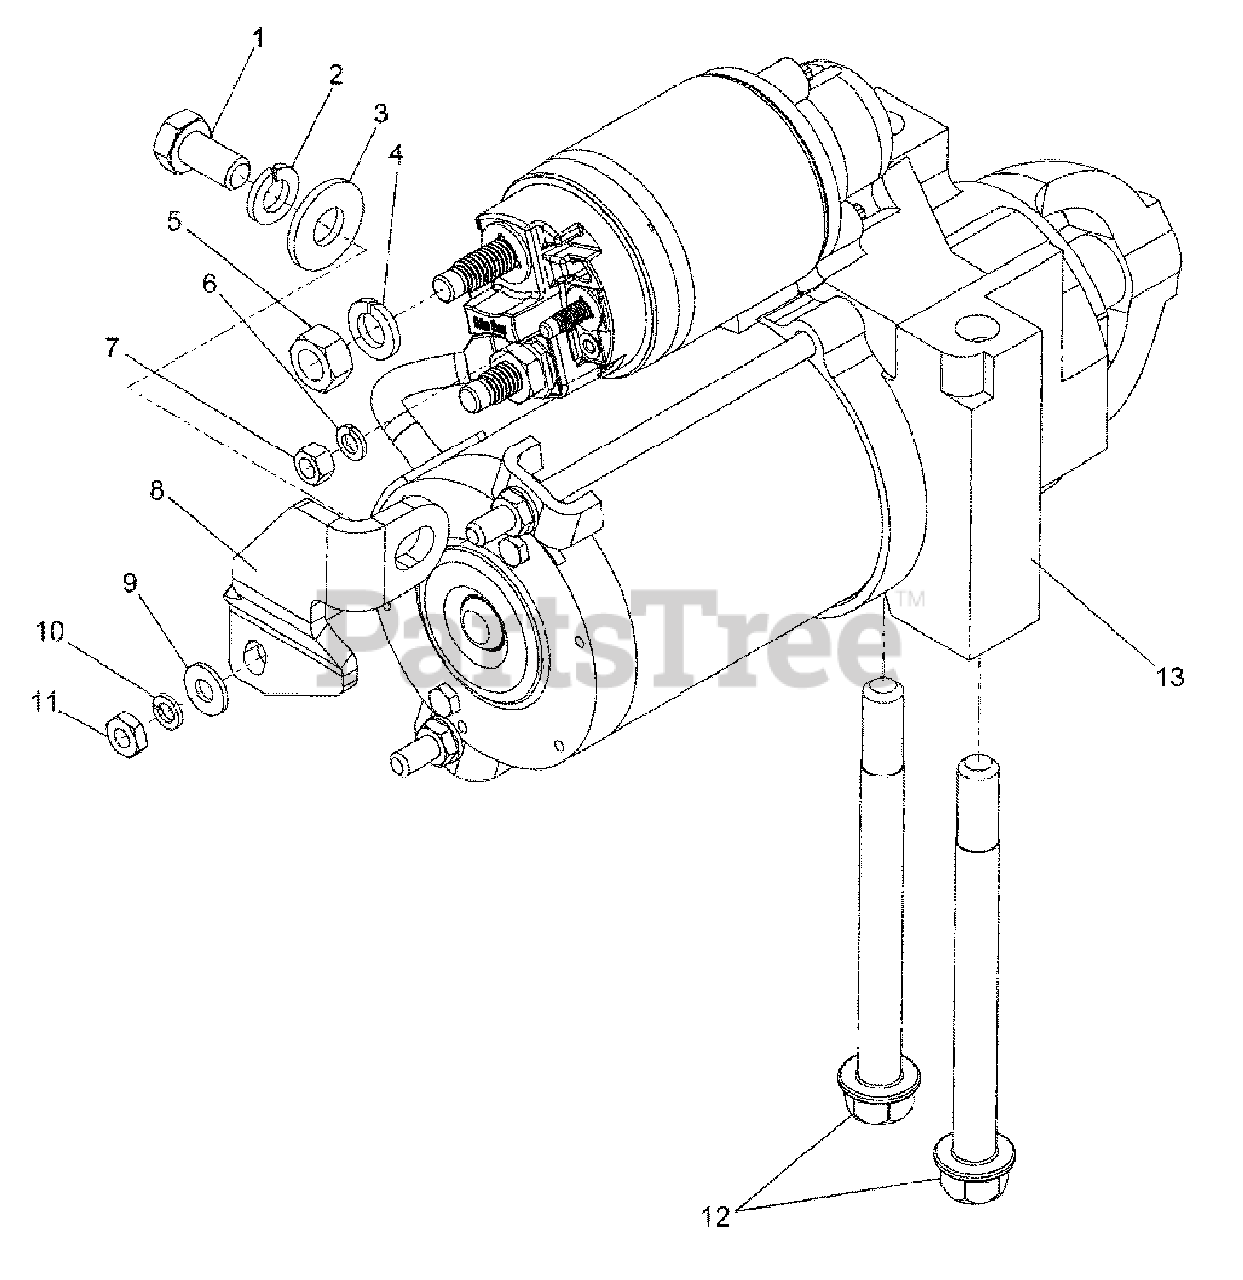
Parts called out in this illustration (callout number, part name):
1	BOLT
2	WASHER-LOCK
3	WASHER-FLAT
4	WASHER-LOCK
5	NUT
6	WASHER-LOCK
7	NUT
8	BRACKET-STARTER
9	WASHER-FLAT
10	WASHER-LOCK
11	NUT
12	BOLT
13	STARTER-MOTOR
